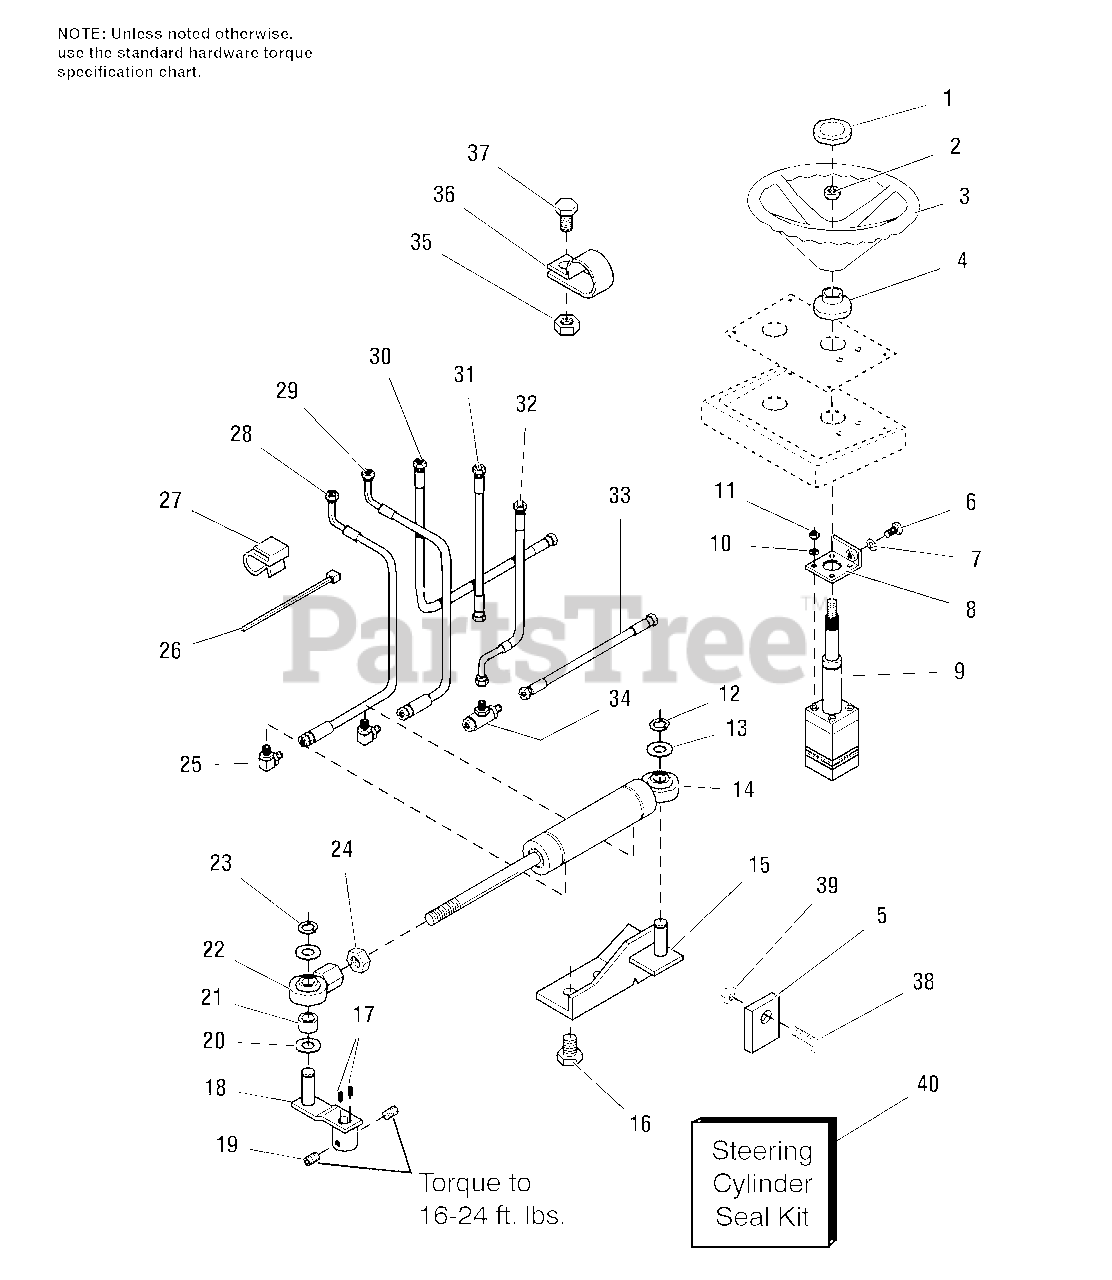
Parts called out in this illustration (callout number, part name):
1	CAP, Steering Wheel
2	NUT, Hex, 5/8-18
3	WHEEL ASSEMBLY, Steering
4	BOOT, Steering Stem
5	UP STOP, Axle
6	CAPSCREW, Hex Hd, M12 x 1.75 x 20mm
7	LOCKWASHER, Int. Tooth, 1/2
8	MOUNTING PLATE ASSEMBLY
9	STEERING UNIT, Hydrostatic
10	LOCKWASHER, 5/16
11	NUT, Hex, 5/16-24
12	RING, Retaining, 5/8
14	CYLINDER, Power Steering
15	BRACKET ASSEMBLY, Cylinder
16	CAPSCREW, Hex. Washer Hd, Taptite 3/8-16 x 3/4
17	KEY, Square, 3/16 x 1-1/4
18	ARM ASSEMBLY, Steering
19	SETSCREW, Hex Socket Hd, 3/8-16 x 1/2
20	WASHER
21	SPACER
22	BALL JOINT ASSEMBLY
23	RING, Retaining, 3/4
24	NUT, Hex Jam, 3/4-16
25	FITTING, Hydraulic, .562 x 8 x .562-18-90
26	TIE, Self Locking .184 x 7.31 LG.
28	HOSE ASSEMBLY, Hydraulic (Steering RT to Cyl.)
29	HOSE ASSEMBLY, Hydraulic (Steering LT to Cyl.)
30	HOSE ASSEMBLY, Hydraulic (Pump to Steering)
31	HOSE ASSEMBLY, Hydraulic (Steering Aux to Lift)
32	HOSE ASSEMBLY, Hydraulic (Steering Out to "T")
33	HOSE ASSEMBLY, Hydraulic (Return "T" to Pump)
34	FITTING, Hydraulic "T"
35	NUT, Hex, Center-Lock, 1/4-20
36	CLAMP, Hose
37	CAPSCREW, Hex Hd, 1/4-20 x 1.00
38	CAPSCREW, Hex Hd, 3/8-16 x 1
39	NUT, Hex Flange, Whiz Lock, 3/8-16
40	CYLINDER SEAL REPAIR KIT
